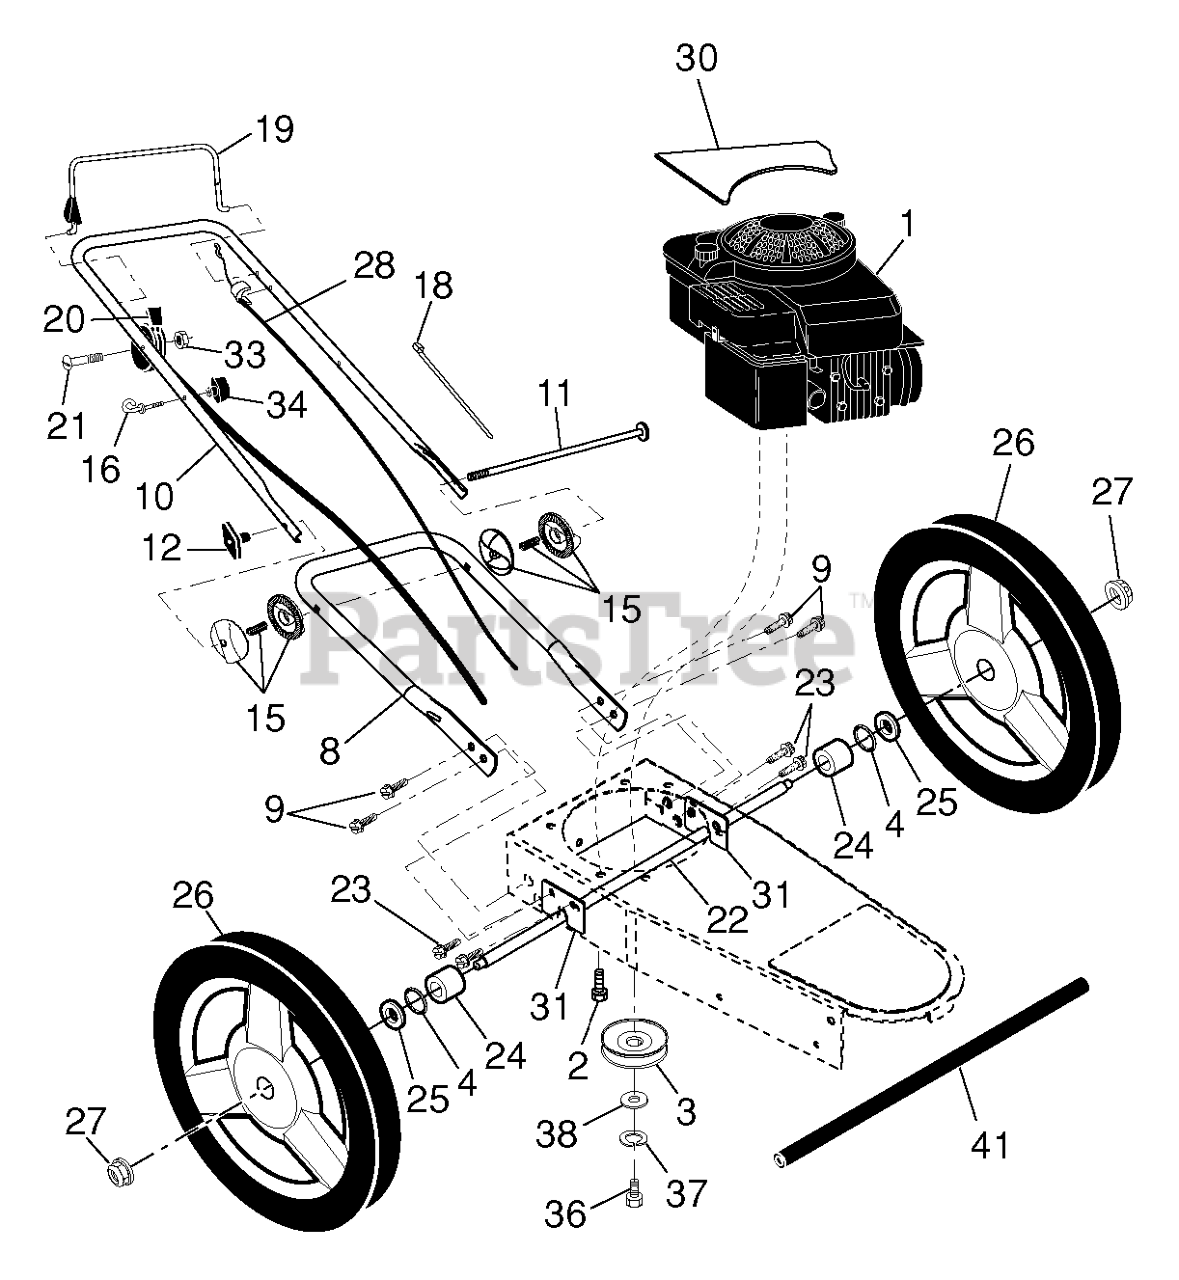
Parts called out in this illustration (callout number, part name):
1	SHIELD, TOP BELT, W/DECALS
2	BELT-TRANS
3	WELDMENT, BLOWER RING, BLK
4	HOUSING, BLOWER
5	HOUSING, IMPELLER
6	IMPELLER, WELDMENT
7	HOSE 7 X 60 CLEAR
8	WELDMENT, TOP PLATE, BLK
9	PIN, RETENTION
10	PIN, MOUNT
12	SPACER,391"ID.375",L.078",WALL
13	CLAMP, HOSE
14	LATCH, PIN, BLK
15	BRACKET, MOUNT, FT-BLK
16	BRACKET, DIVERTER BLK
17	GUARD, RUB, BLK
18	SPRING, DECK DRIVE
19	SPRING, IDLER
20	BUSHING, BRAKE
21	HUB, BEARING
22	MOUNT.REAR.COLLECTION.BLACK
23	WELDMENT, IDLER, BLK
24	KEEPER, BELT
26	SHAFT, IMPELLER
27	SHAFT, SPINDLE
28	Drive Cable, Trimmer
30	PULLEY, DRIVE
31	PULLEY, IDLER, BACKSIDE, 3.25"
33	KEY, 3/16 X 1/2
35	DECAL, EURO WARNING
36	EURO DECAL, IMPELLER
37	BRACKET.LINER.OUTBOARD
38	BRACKET.LINER.INBOARD
39	HCS 5/16-18 X 1/2 GR 5 ZD
40	BOLT, HCS 3/8-16X1-3/4
41	HCS 3/8C X 1 1/2
42	HCS 3/8C X 1 1/4 GR5
43	HCS 5/16C X 3/4
44	HCS 5/16C X 1
45	BOLT 5/16C X 3/4" CARRIAGE
46	RHSNB 5/16C X 1
47	RHSSNB, 1/4-20X5/8
48	HHFS 3/8-16 X 1.25 GD 5
49	BOLT, HEX 3/8-24 X 1.25 GR 8
50	JAM NUT 1/4C (2 2 PW01)
51	NUT 5/16-18 HEX JAM ZD
52	NUT HEX 3/8-16 NYLON, THIN
53	NUT 5/16-18 TEE
54	5/16-18 NYLOC FLANGE NUT
55	NUT 3/8-16 HEX FLG NYLOC ZD
56	WASHER .787 X 1.125 X .06
57	WASHER 1/4 FLAT
58	SLW 3/8 STD
59	WASHER 3/8 SAE FLAT
60	WASHER, HARDENED
61	FLAT WASHER 5/16 SAE
62	KEY-SQ. 3/16 X 1 1/2
